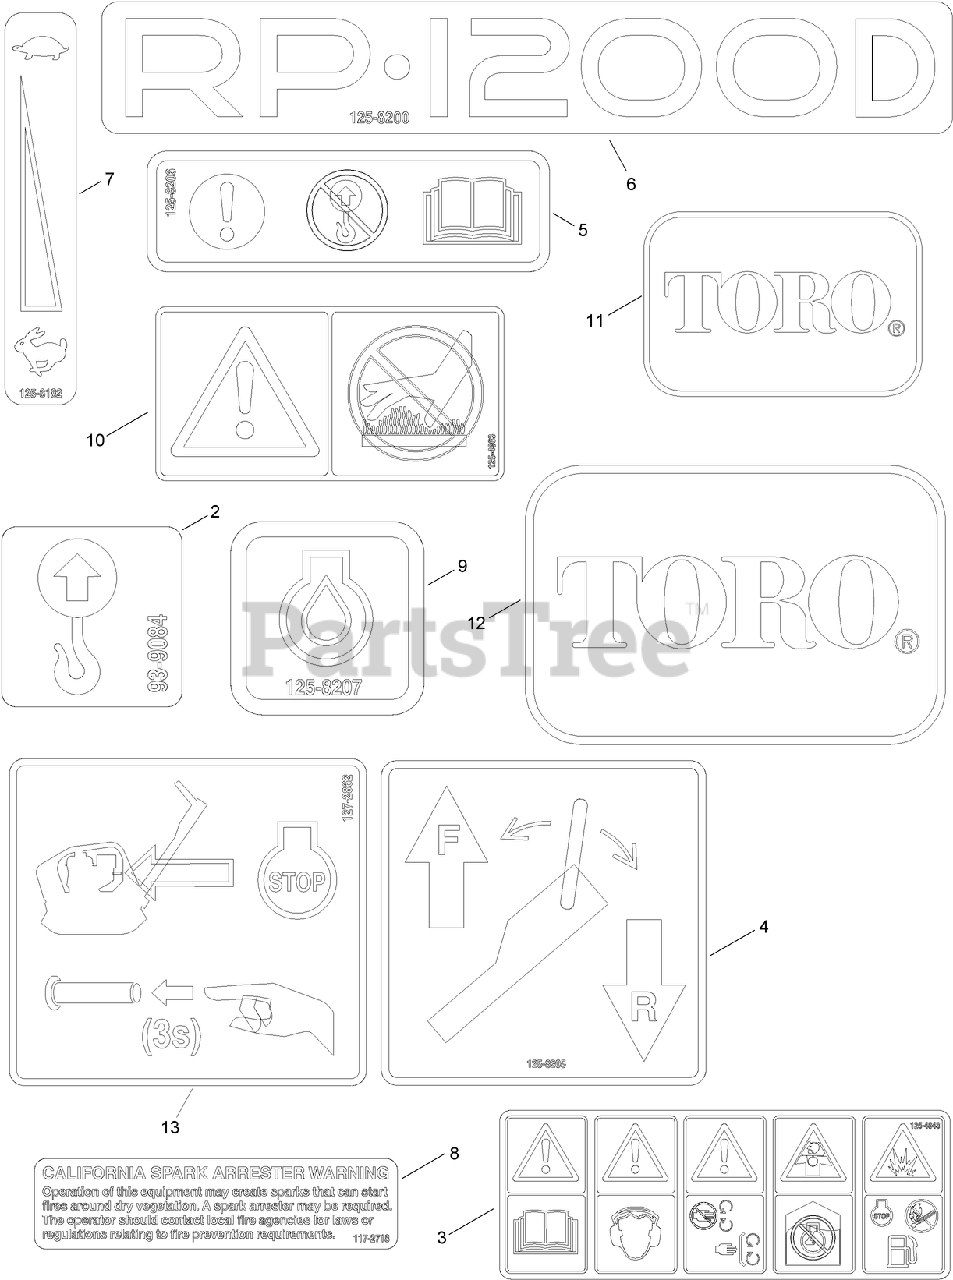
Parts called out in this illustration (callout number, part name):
2	DECAL-POINT, LIFT
3	DECAL-WARNING, PLATE
4	DECAL-OPERATION
5	DECAL-CAUTION
7	DECAL-THROTTLE
8	DECAL-ARRESTER, SPARK
9	DECAL-OIL, ENGINE
10	DECAL-SURFACE, HOT
11	DECAL
13	DECAL-STOP, ENGINE
